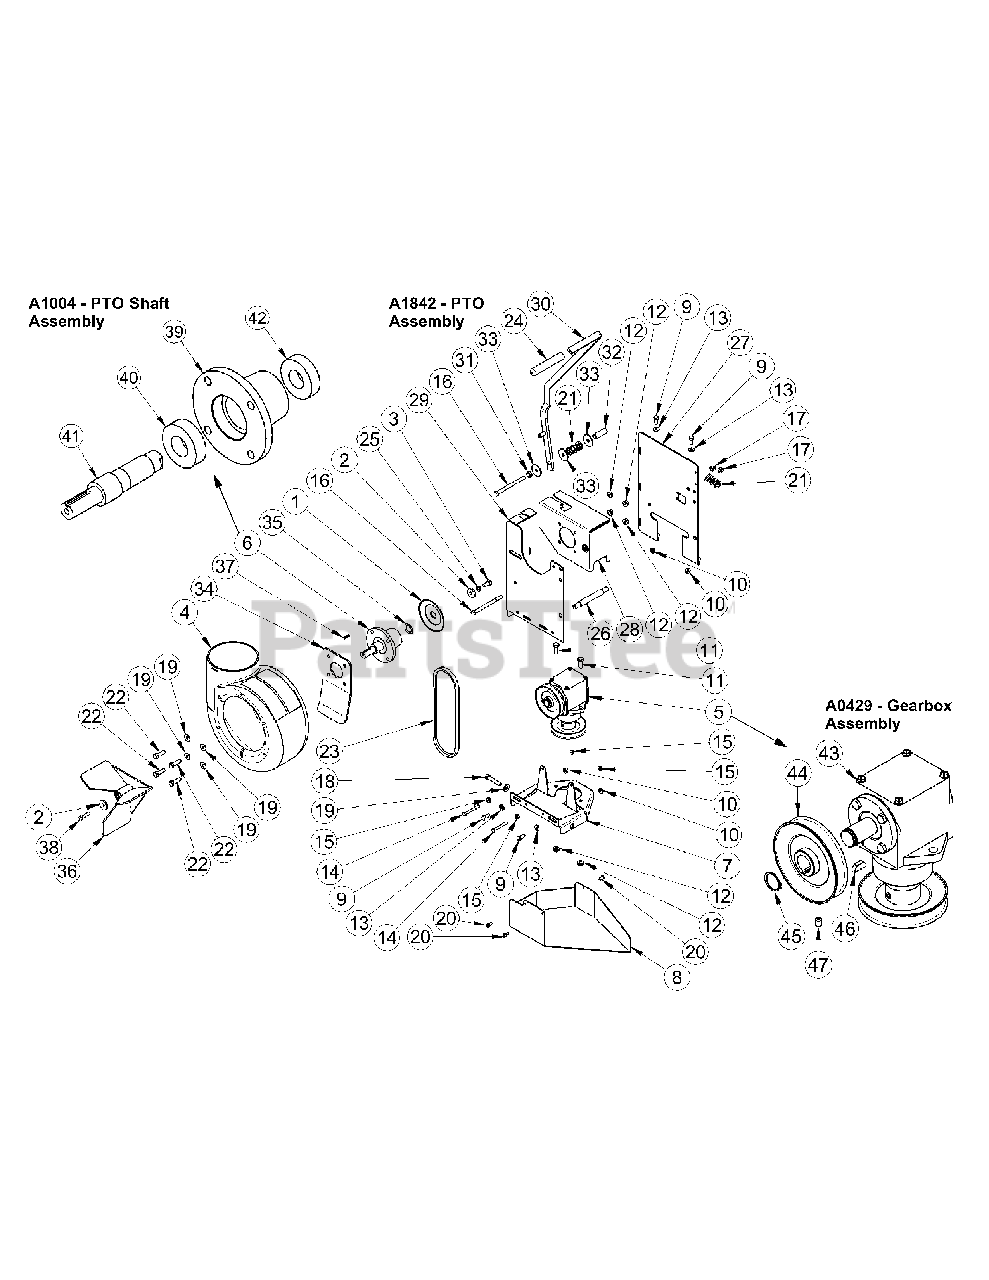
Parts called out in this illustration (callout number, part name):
1	BLOWER PULLEY
2	WASHER-1.187 OD
3	HEX BOLT-3/8-16 X
4	BLOWER HOUSING
5	GEAR BOX ASSEMBLY
6	PTO SHAFT ASSEMBLY
7	BASE PLATE ASSEMBL
8	GEAR BOX PULLEY GU
9	SCREW-HEX HEAD 5/1
10	NUT-FLANGE 5/16-18
11	BOLT-HEX 3/8-16 X
12	FLANGE-3/8-16
13	WASHER-FLAT
14	SCREW-HEX HEAD 1/4
15	NUT-FLANGE 1/4-20
16	BOLT-HEX 3/8-16 X
17	NUT-NYLOCK 3/8-16
18	BOLT-HEX 3/8-16 X
19	WASHER-FLAT
20	SCREW-HEX HEAD 1/4
22	BOLT-HEX 3/8-16 X
23	BELT-4L300DWK KEVL
24	HANDLE GRIP 5/8 BL
25	WASHER-LOCK 3/8
26	PTO ARM MOUNT ROD
27	RT PTO ARM
28	BLOWER MOUNT BRACK
29	RT PTO ARM
30	PTO HANDLE ASSEMBL
31	SPACER BUSHING
32	SPACER BUSHING
33	WASHER-1-1/2 X 3/8
34	STIFFENER PLATE/BLOWER HOUSING
35	WASHER-FLAT
36	IMPELLER BLADE ASSEMBLY
37	KEYWAY-3/16 X 3/4
39	PTO SHAFT HOUSING
40	BEARING-LARGE
41	PTO SHAFT
42	BEARING
43	GEAR BOX-RIGHT ANG
44	GEAR BOX PULLEY AS
45	SNAP RING-RETAININ
46	WOODRUFF KEY #9
47	SCREW-SET 5/16-18
A1842	PTO ASSEMBLY-3 BLADE
A1004	PTO SHAFT ASSEMBLY
A0429	GEAR BOX ASSEMBLY
